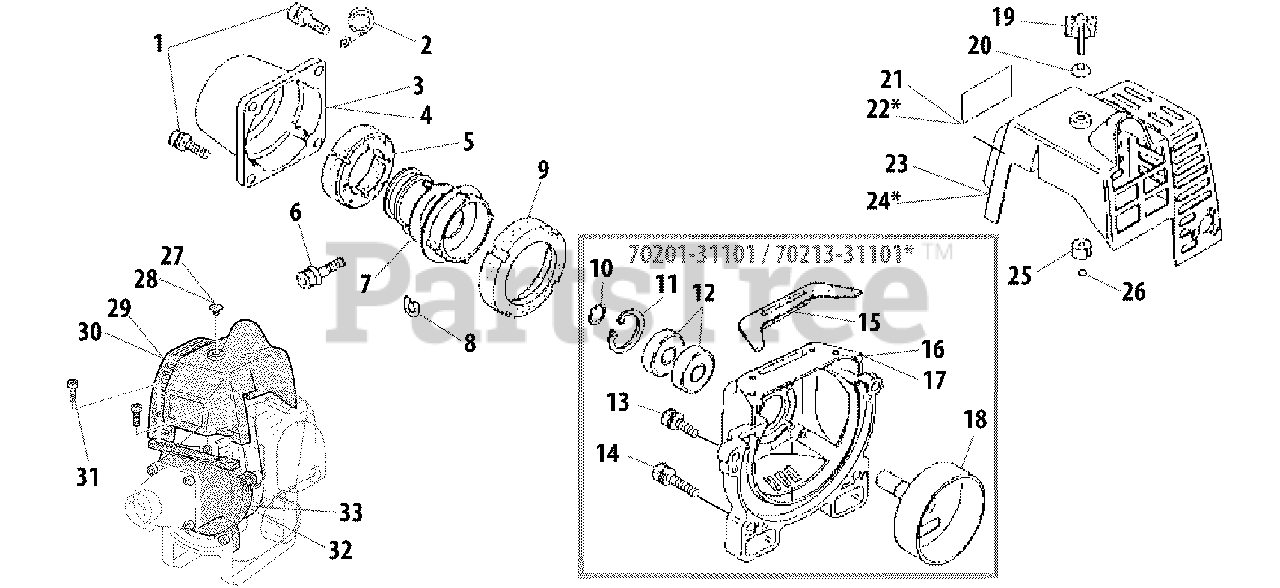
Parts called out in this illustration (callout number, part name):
1	BOLT M5×20
2	HOLDER, THROTTLE CABLE
3	COVER, AV CUSHION (RED)
4	COVER, AV CUSHION (BLUE)
5	CUSHION, FRONT
6	BOLT M5×25
7	JOINT
8	D-WASHER
9	HOLDER, REAR CUSHION
10	RING, SNAP WR10
11	RING, SNAP Ø26
12	BEARING, BALL 6000 DDU
13	BOLT M5×25
14	BOLT M5×16
16	COVER, FAN
17	CASE, FAN - BLUE
18	DRUM, CLUTCH
19	THUMBSCREW
20	WASHER, CONE M6
21	NAME LABEL
23	COVER, ENGINE
24	COVER, ENGINE - BLUE
25	INSULATOR 5 MM
26	CLIP
27	PLUG
28	PLUG (BLUE)
29	COVER, ENGINE
30	COVER, ENGINE - BLUE
31	BOLT M5×16
32	COVER, FAN (RED)
33	COVER, FAN (BLUE)
A	FAN CASE ASSY - RED
A	FAN CASE ASSY - BLUE
